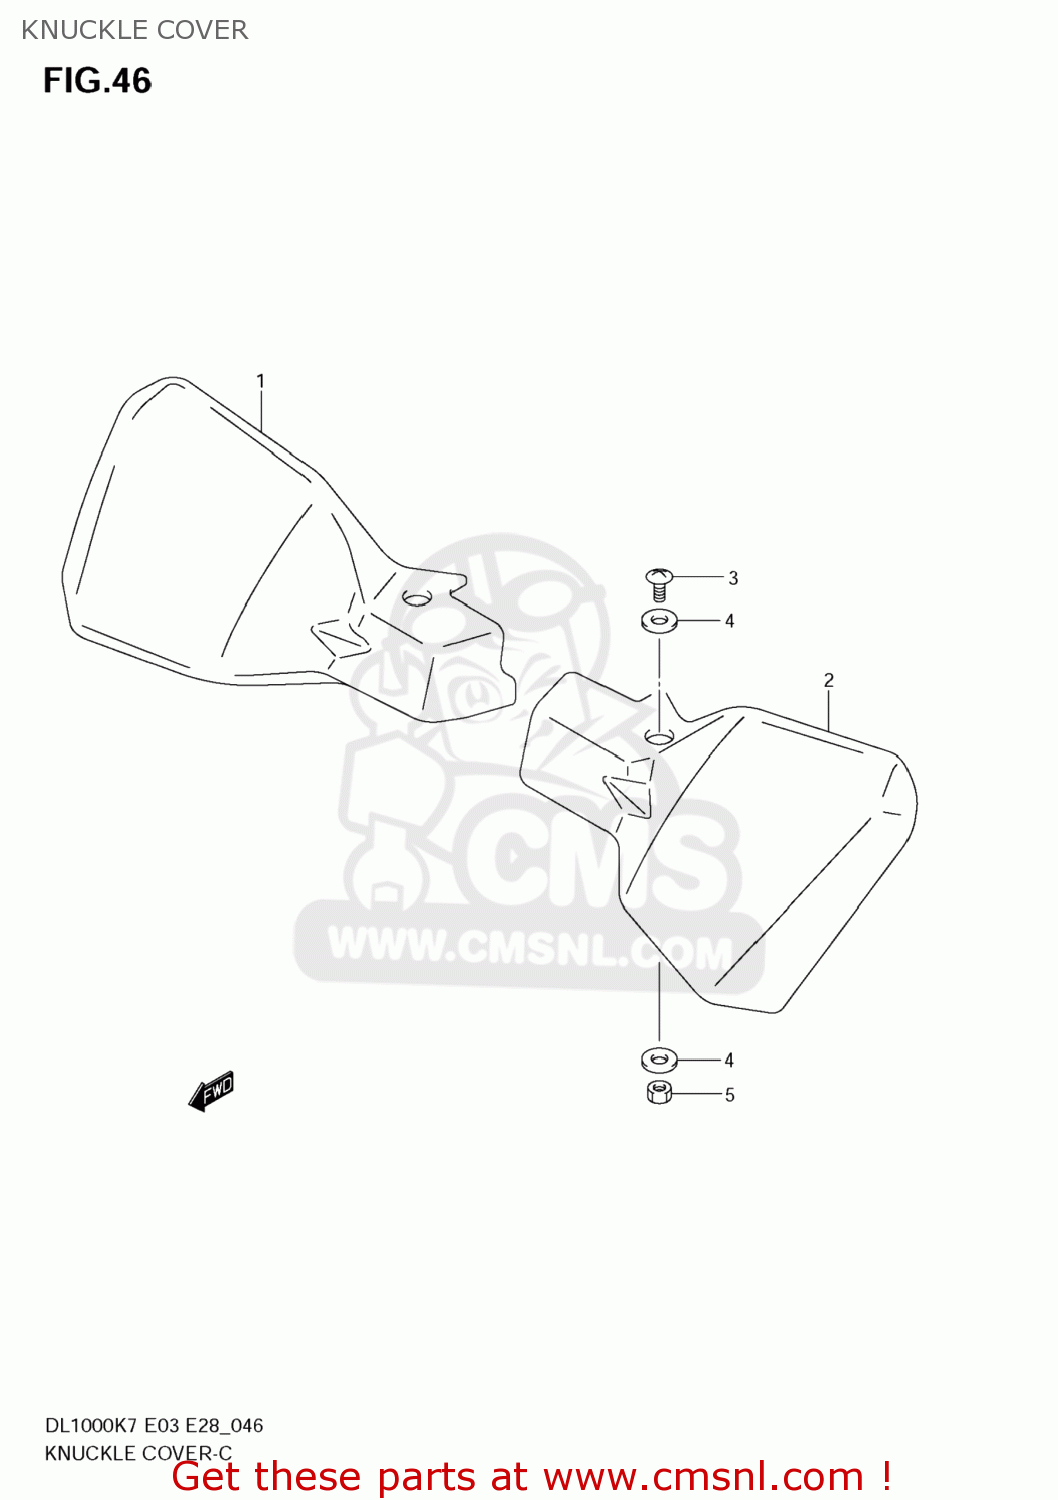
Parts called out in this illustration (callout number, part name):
1	COVER,KNUCKLE,
2	COVER,KNUCKLE,L
3	SCREW(6X10)
4	WASHER(6.5X16X1.6)
5	NUT
